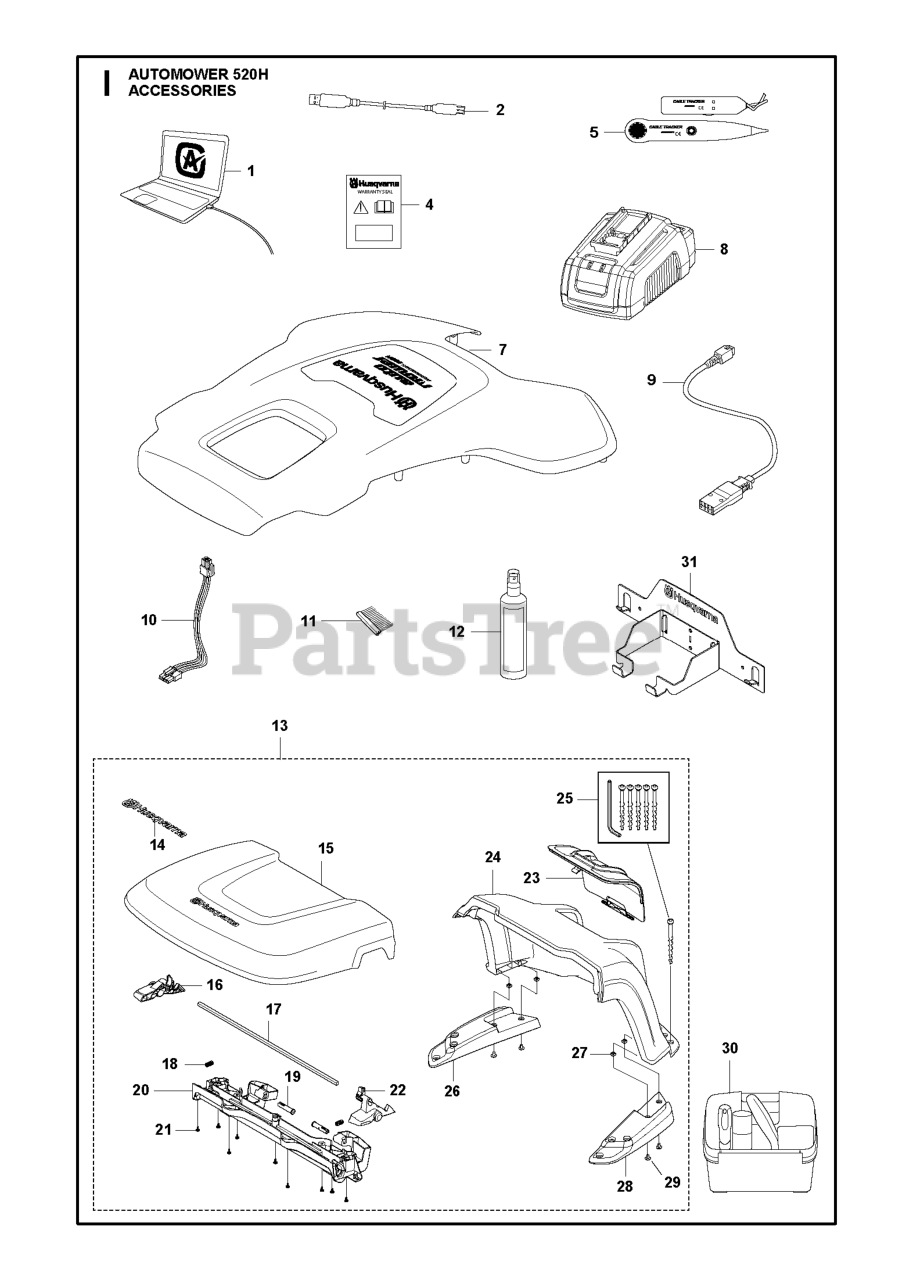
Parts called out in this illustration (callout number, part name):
2	CABLE WHITE ALT GREY
4	LABEL WARRANTY SEAL DEALER
5	TEST EQUIPMENT
7	Body
7	BODY KIT SPARE PART TOP COVER
8	CHARGER BATTERY TEST
9	CABLE ASSY QUICK CHARGER
10	WIRING ASSY BATTERY CABLE
11	WHEEL BRUSH REFILL KIT
12	AUTOMOWER ACCY
13	COVER
14	DECAL
16	HANDLE RELEASE LEFT
17	ROD
18	SPRING SPRING CAP
19	HINGE PIN
20	BEAM
21	SCREW 14MM
22	HANDLE RELEASE RIGHT
23	HATCH
25	Screws
26	SUPPORT BASE LEFT
27	NUT
28	SUPPORT BASE RIGHT
29	SCREW IHPANM M6X25 4.6 ZP-BC
30	CLEANING AND MAITENANCE KIT AM
31	HANGER
